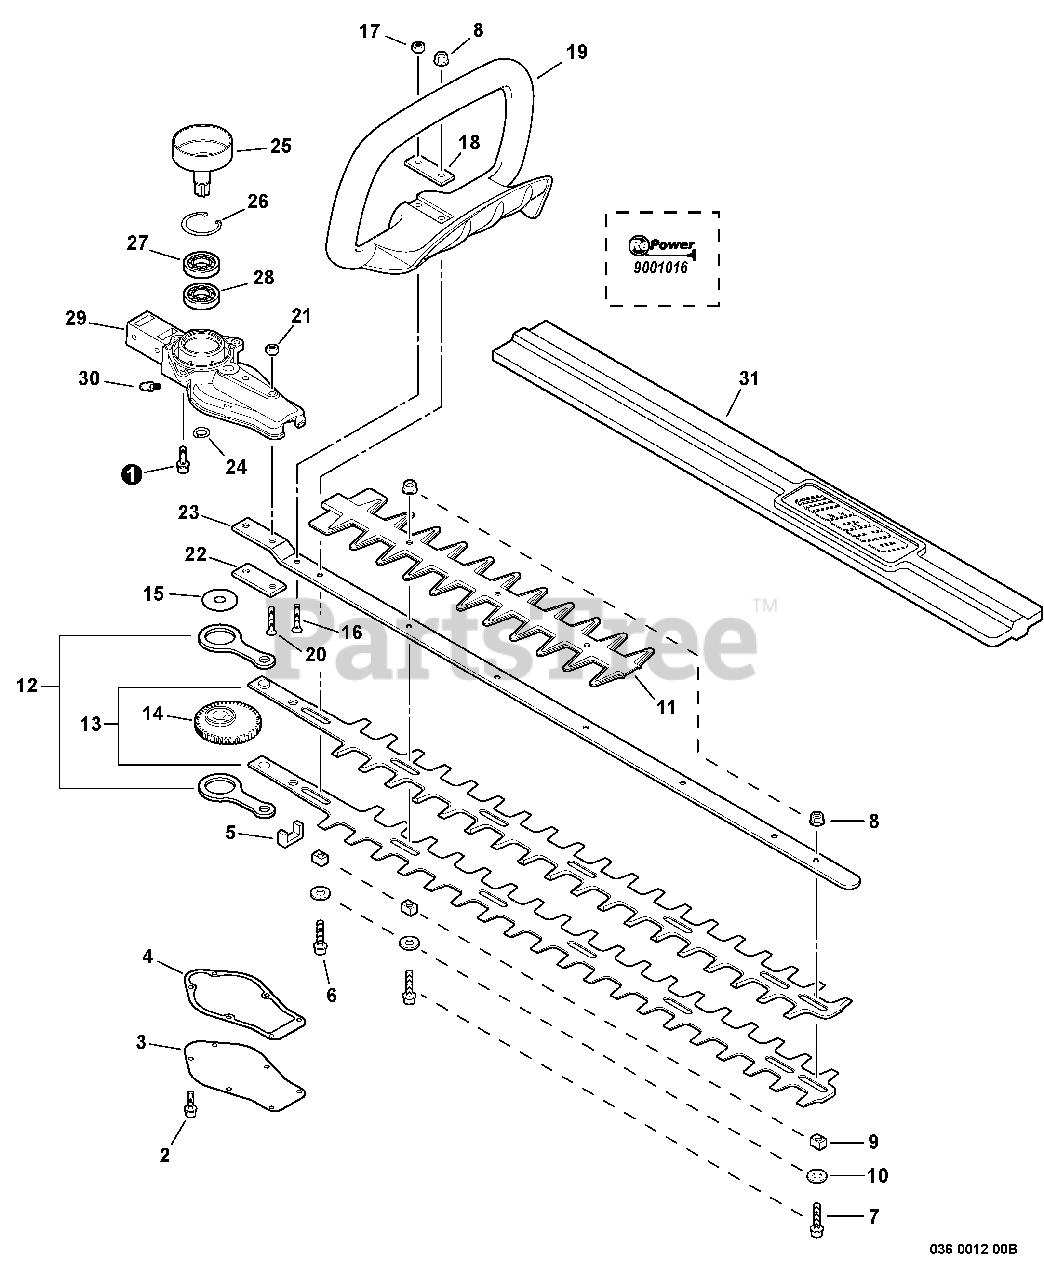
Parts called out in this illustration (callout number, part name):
1	BOLT 5×20
2	BOLT 4×10
3	COVER, GEAR CASE
4	GASKET, GEAR CASE
6	BOLT 5×40
7	BOLT 5×20
8	NUT, FLANGE M5
9	GUIDE, BLADE 5
10	WASHER 5
11	GUARD, CUTTER BLADE
12	CONROD
13	CUTTER 24"
16	SCREW 5×30
17	NUT, LOCK M5
18	PLATE, EYE
19	HANDLE, FRONT
20	SCREW 6×25
21	NUT, HEX M6
22	PLATE, EYE
23	SUPPORT, BLADE 24"
24	RING, SNAP 14
25	DRUM, CLUTCH
26	RING, SNAP 35
27	BEARING, BALL 6202
28	BEARING, BALL 6202
29	GEAR CASE ASSY
30	FITTING, GREASE
31	SCABBARD
32	CUTTING HEAD KIT
